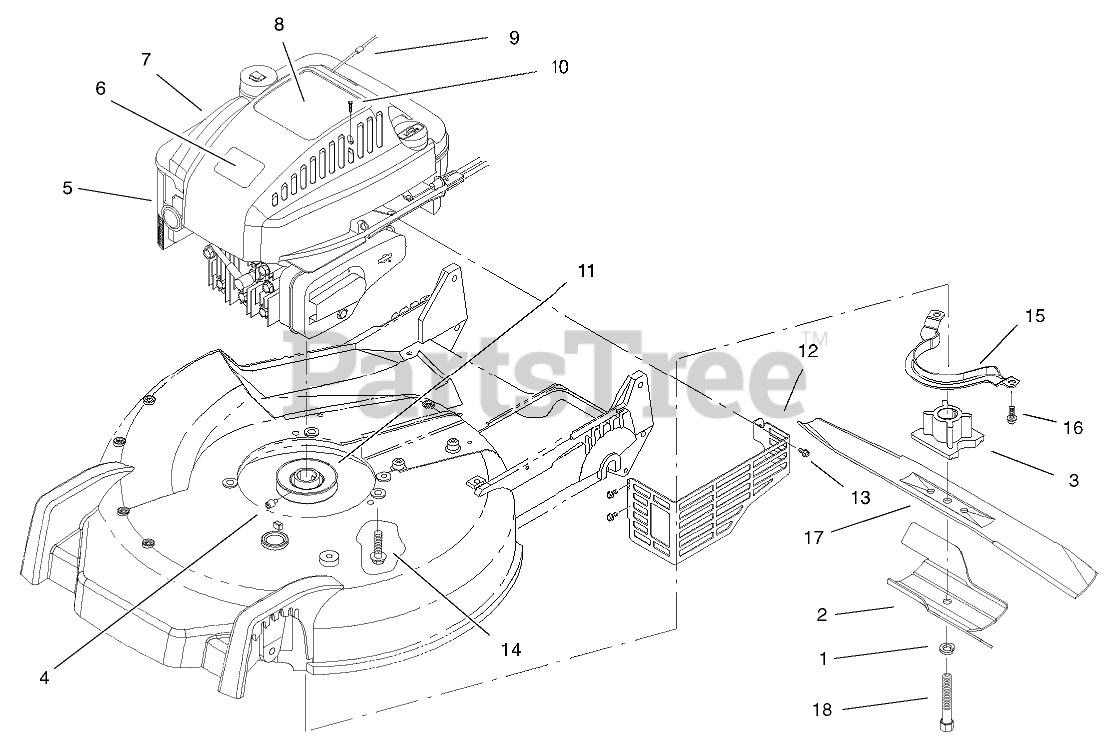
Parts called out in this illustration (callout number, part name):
1	WASHER-LOCK
2	ACCELERATOR-BLADE
3	RETAINER-BLADE
4	SCREW-SET
6	Decal
7	SHROUD-ENGINE
8	DECAL - RECOIL
9	STOP-ROPE
10	SCREW-PPH
11	PULLEY
12	SHIELD-MUFFLER
13	SCREW-TAPTITE
14	SCREW-HWH
15	BRACKET-GUIDE, BELT
16	SCREW-HWHTF
17	BLADE
18	SCREW-BLADE
